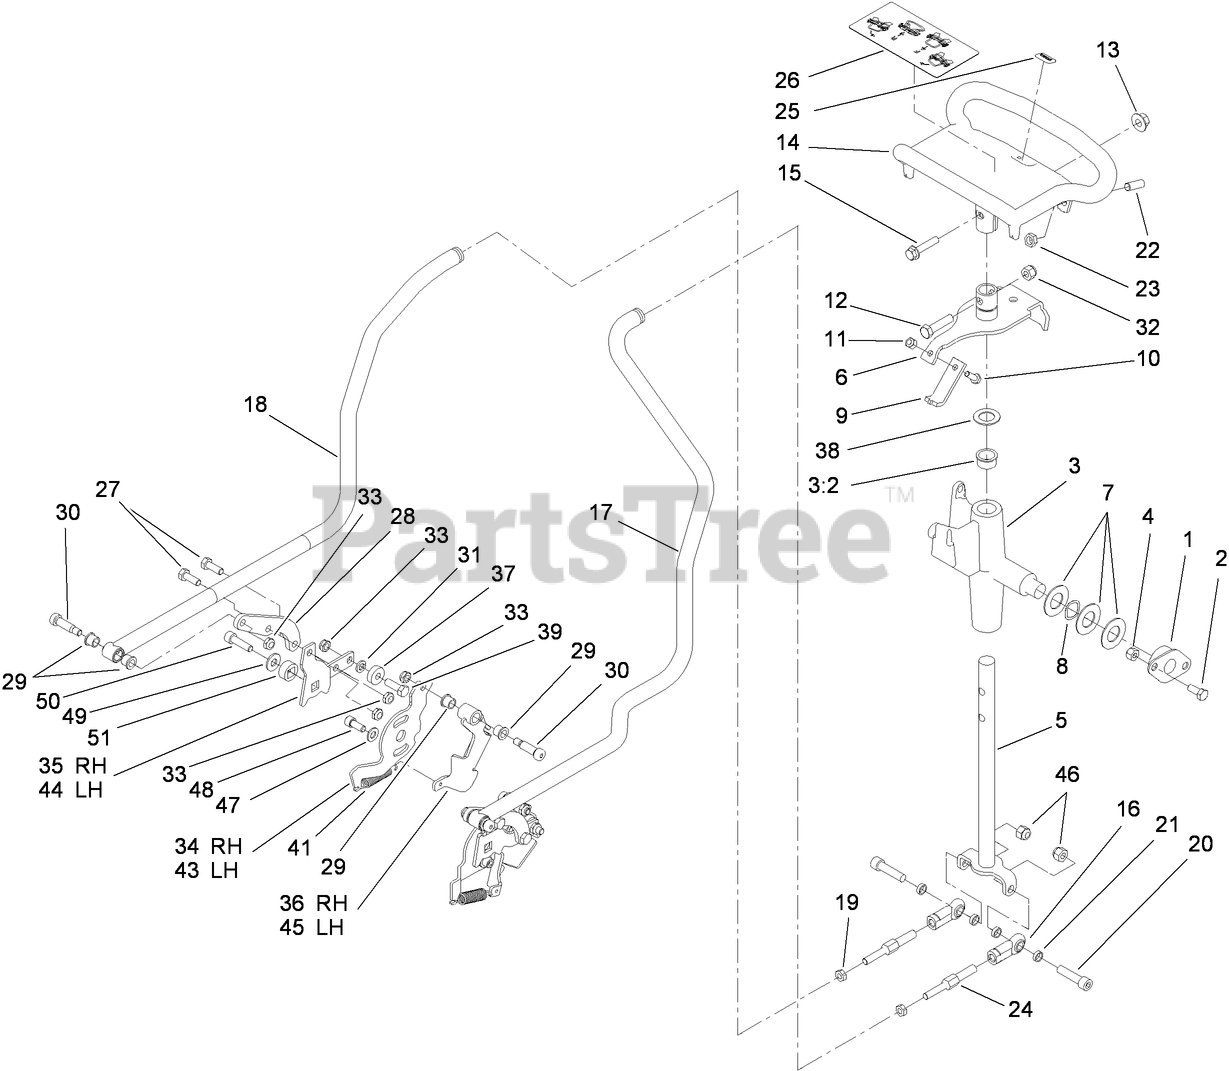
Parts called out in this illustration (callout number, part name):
1	BUSHING
2	SCREW-HH
3	CONTROL SUPPORT ASM
3:2	BEARING-FLANGE
4	NUT-LOCK, NI
5	ROD-DRIVE
6	LEVER-PIVOT
7	WASHER-FLAT
8	WASHER-SPRING, WAVE
9	PLATE-NEUTRAL
10	SCREW-HH
11	NUT-LOCK, NI
12	SCREW-HH
13	NUT-FLANGE
14	HANDLE-CONTROL
15	SCREW-HHF
16	JOINT-BALL END, LH
17	ROD-CONTROL, LH
18	ROD-CONTROL, RH
19	NUT-JAM
20	SCREW-HSH
21	SPACER-PLATE, RETAINING
22	SCREW-SET
23	NUT-JAM
24	LINK-CONTROL, ADJUSTMENT
25	DECAL
26	DECAL-TRACTION
27	SCREW-HH
28	PLATE-ADAPTER, CONTROL, RH
29	BUSHING-FLANGE
30	BOLT-SHOULDER
31	WASHER-LOCK
32	NUT-LOCK, NI
33	NUT-LOCK, NI
34	PLATE-BASE, RH
35	PLATE-ARM, RETURN
36	PIVOT-RH
37	BEARING-BALL
38	WASHER-THRUST
39	SCREW-HH
41	SPRING-EXTENSION
43	PLATE-BASE, LH
44	PLATE-ARM, RETURN, LH
45	PIVOT-LH
46	NUT-LOCK, NI
47	WASHER-PLAIN
48	SCREW-HSH
49	WASHER-FLAT
50	SCREW-HSH
51	LOCK-TRUNION
